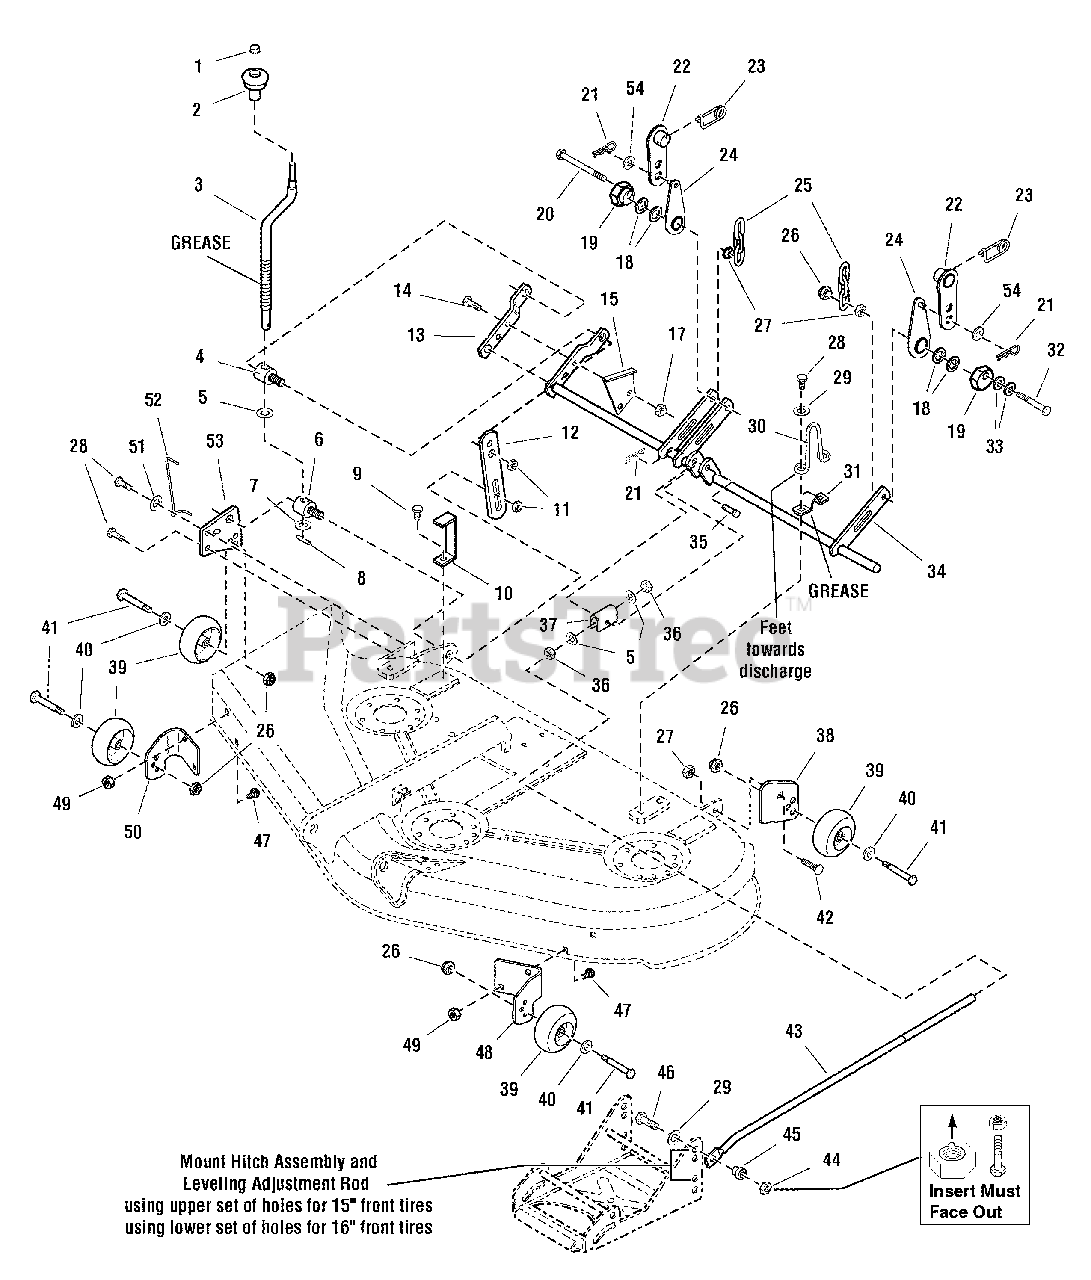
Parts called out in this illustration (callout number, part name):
1	NUT, Push Pal Stud Capped
2	KNOB, Spinner
3	CRANK, Height Adjustment
5	WASHER, 1/2
7	WASHER, Detent
8	PIN, Spring
9	SCREW, Hex Washer Head Taptite, 5/16-18 x 3/4
10	BRACKET, Upstop
11	NUT, Hex Flange, Two-Way Lock, 1/2-13
12	STOP, Height Adjust
13	ARM, 1-1/4 Wide 6-41/64 Long
14	CAPSCREW, Hex Head, 5/16-18 x 1 1/4
15	BRACKET, Height of Cut
17	NUT, Whiz Lock, 5/16-18 NC-2B
18	WASHER,1.000(1.01IDX1.50ODX.05THK)
19	NUT, Hex Adjusting, 11/16
20	CAPSCREW, Hex Head, 3/8-16 x 3 G5
21	CLIP, Hair Pin Spring Wire 1-5/8 Long
22	HANGER & SPACER ASSEMBLY
23	RETAINER, Pin Spring
24	HANGER & PIN ASSEMBLY
25	CHAIN, Link 3 Links 4-1/2 Long
26	NUT, Hex Flange ESNA, 3/8-16
27	NUT, Hex Flange Whiz Lock Small, 3/8-16
28	SCREW, Hex Washer Head Taptite, 5/16-18 x 1-1/4
29	WASHER, 3/8
31	STRAP
32	CAPSCREW, Hex Head, 3/8-16 x 2-1/4 G5
33	WASHER, 3/8
34	SHAFT ASSEMBLY, Rocker 44"
35	PIN, Round Head Drilled, 3/8 x 2
36	NUT, Hex Jam, 1/2-13
38	SUPPORT, Roller LH
39	WHEEL, 2 Wide
40	WASHER, 1/2
41	BOLT, Wheel, 3/8-16 x 2-25/32
42	CARRIAGE BOLT, 3/8-16 x 1 G5
43	ROD, Adjustment, 28 Long
44	NUT, Hex Flange, 3/8-16
46	CAPSCREW, Hex Head, 3/8-16 x 1-3/4
47	CARRIAGE BOLT, 5/16-18 x 7/8 G5
48	BRACKET, Wheel Guage LH
49	NUT, Hex Flange Whiz Liock Large, 5/16-18
50	BRACKET, Wheel Guage RH
51	WASHER, 5/16
52	ROD, Indicator, 6-5/16 Long
53	SUPPORT, Plate
54	WASHER, 3/8
